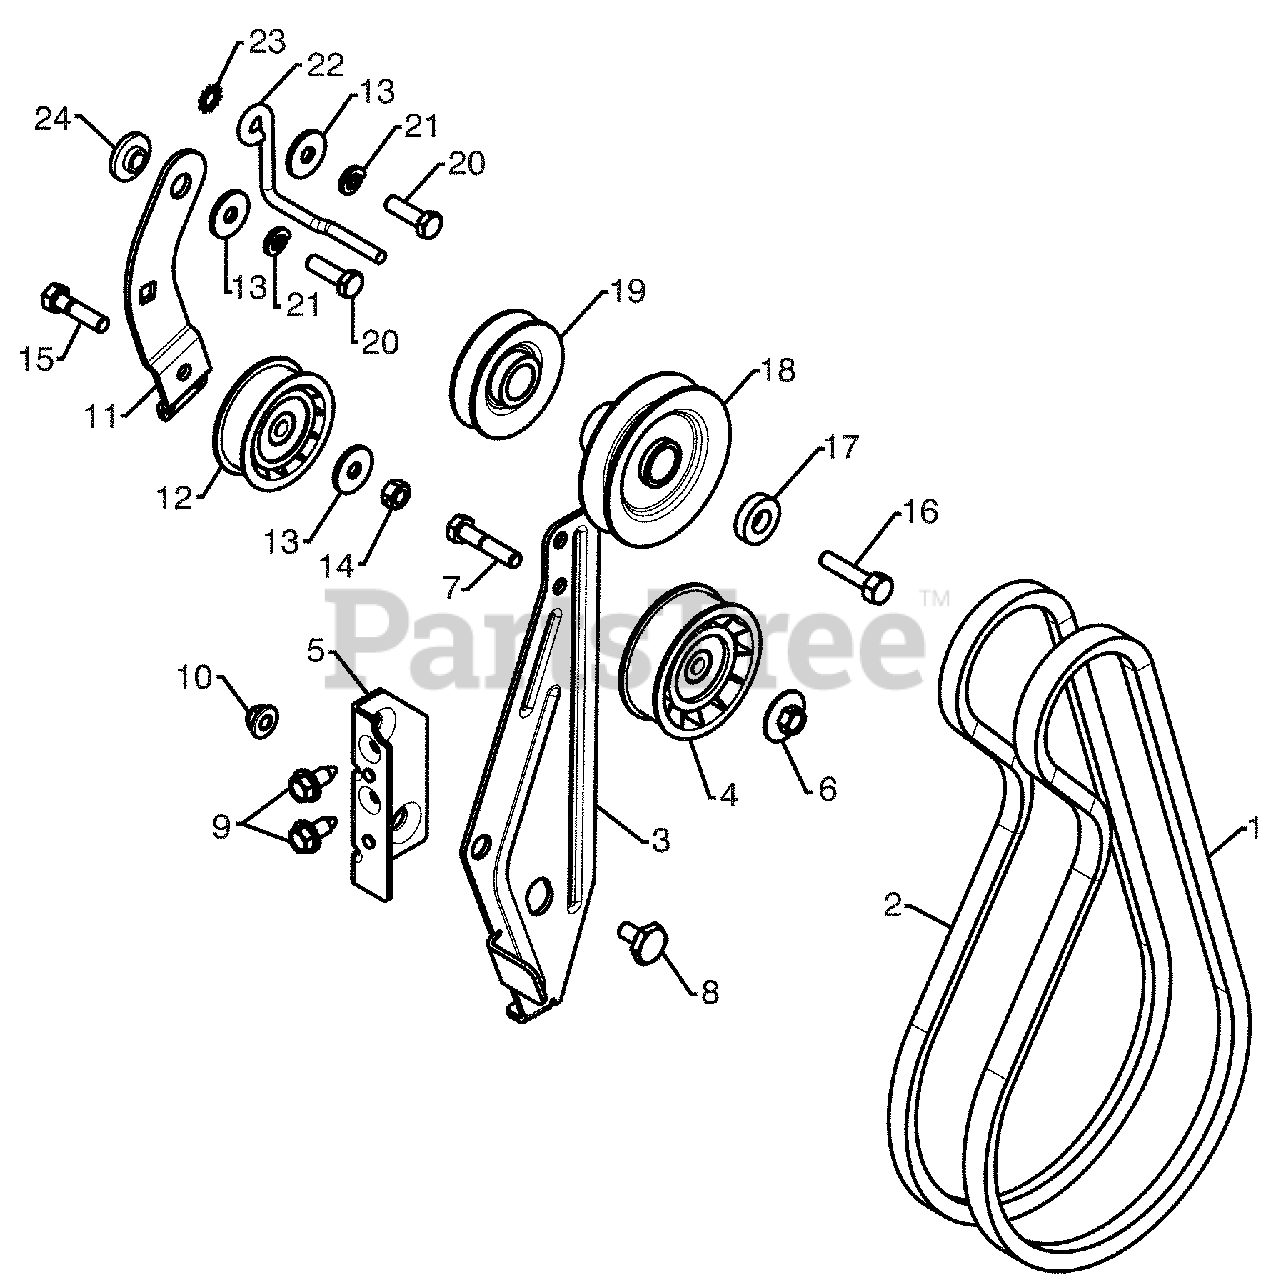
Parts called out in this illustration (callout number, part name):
1	IMPELLER BELT
2	TRACTION BELT
3	IDLER ARM BRACKET
4	IDLER PULLEY
5	IDLER BRACKET
6	NUT 5/16-18
7	SCREW 5/16-18 X 1.50
8	SHOULDER BOLT 5/16-18 X .50
9	SCREW 5/16-18 X .625
10	NUT 5/16-18 NYLOCK
11	TRACTION IDLER BRACKET
12	TRACTION PULLEY
14	NUT 5/16-18
15	SCREW 5/16-18 X 1.25
16	SCREW 3/8-24 X 1.375
18	PULLEY ENG IMPELLER
19	PULLEY ENG TRACTION
20	SCREW 5/16-24 X 1.00
21	LOCKWASHER 5/16
22	BELT GUIDE
23	LOCKWASHER 5/16
24	IDLER BUSHING
